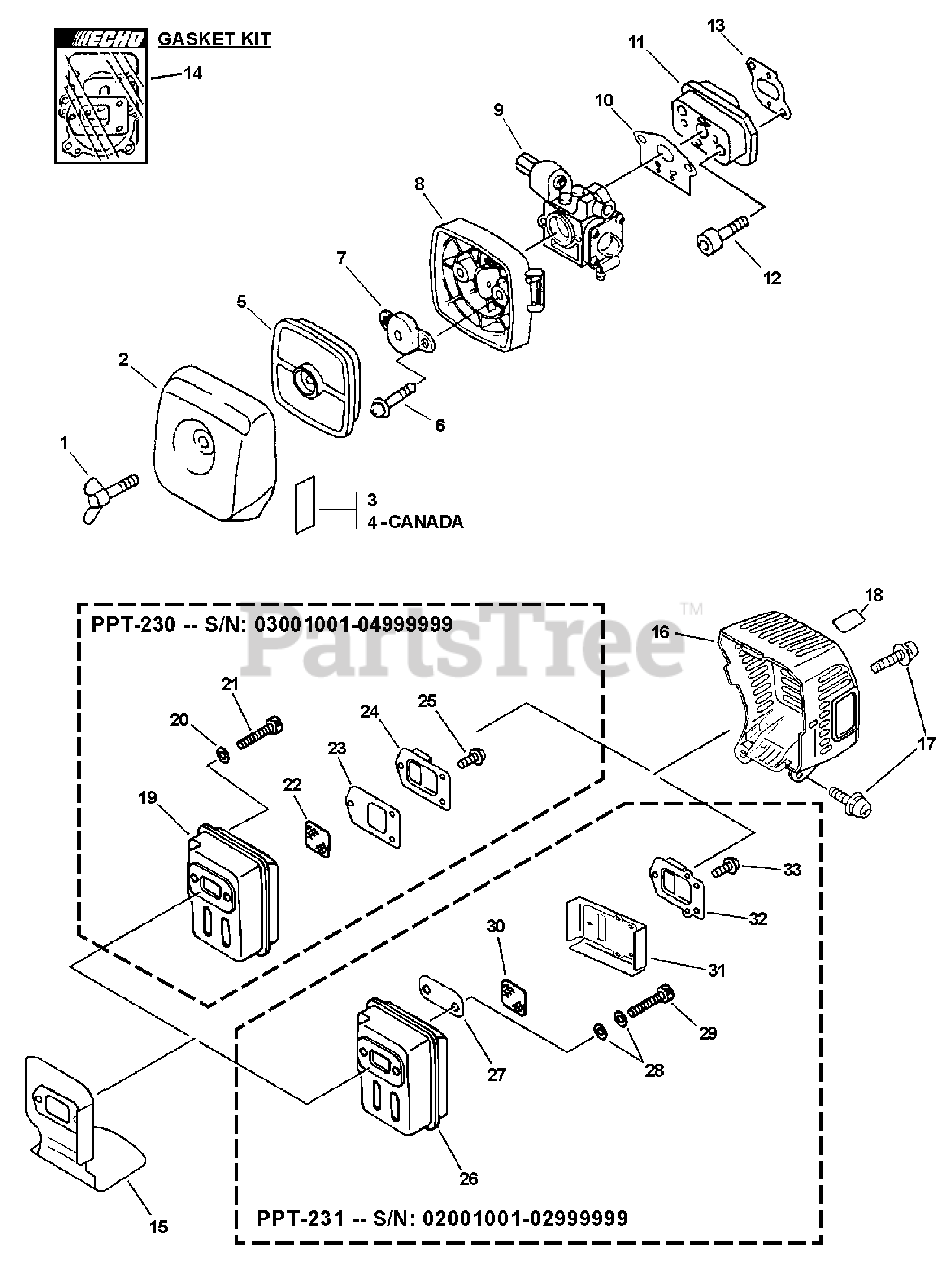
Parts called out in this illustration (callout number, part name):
1	BOLT, WING 5×20
2	COVER, AIR FILTER - BLACK
3	LABEL, CHOKE
4	LABEL, CHOKE
5	FILTER, AIR - SINGLE LAYER
6	SCREW 5×60
7	PLATE, PREVENT
8	CASE, AIR FILTER - BLACK
9	CARBURETOR - RB-K57A
10	GASKET, CARBURETOR
11	INSULATOR, INTAKE
12	BOLT 5×25
13	GASKET, INTAKE
14	GASKET KIT
15	HEAT SHIELD, EXHAUST
16	COVER, EXHAUST
17	BOLT 5×12
18	LABEL, CAUTION - HOT
20	WASHER, FLAT 5.5×10×0.8
21	BOLT 5×55
22	SCREEN, SPARK ARRESTER
23	GASKET, EXHAUST
24	GUIDE, EXHAUST
25	SCREW 4×12
26	MUFFLER
27	PLATE, EYE
28	CONICAL WASHER
29	BOLT 5×55
30	SCREEN, SPARK ARRESTER
31	GASKET, EXHAUST
32	GUIDE, EXHAUST
33	SCREW - 4×10
